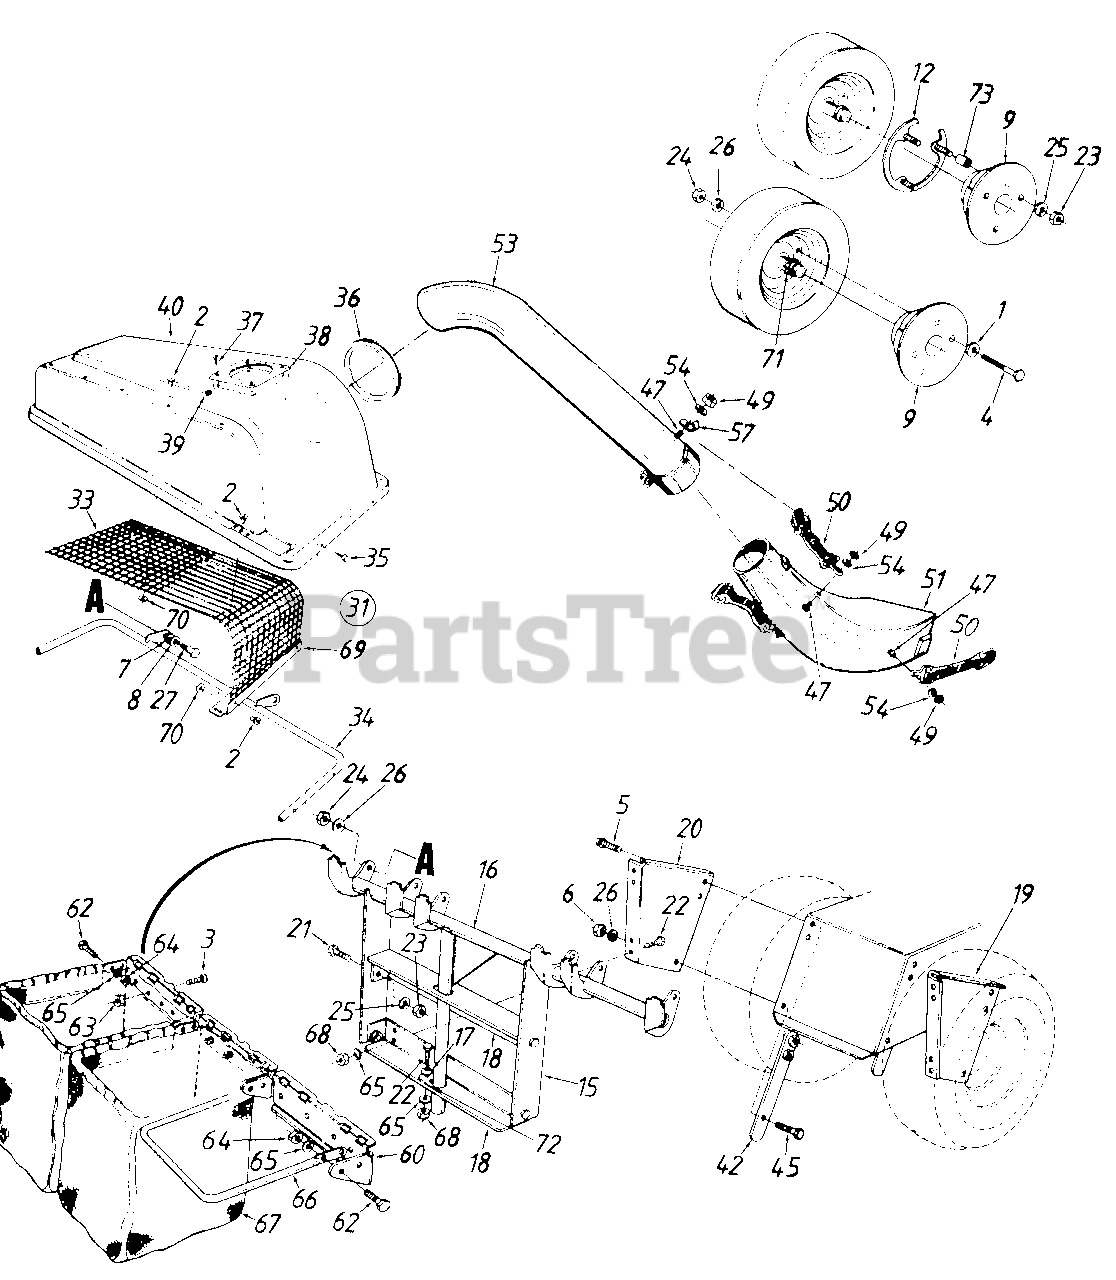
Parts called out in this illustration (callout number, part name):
1	Fl-Wash. .385" I.D.
2	Pop Rivet
3	Truss Mach. Scr. #10-24 x .38" Lg.
4	Hex Bolt 3/8-16 x 4.5" Lg.
5	Hex Wash. Hd. Tap Scr. 5/16-18 x .62
6	Hex Nut 3/8-24 Thd.
7	Bell-Wash. .515" l.D.
8	Fl-Wash. .510" l.D.
9	Wheel Weight
12	Wheel Weight Snap Ring
15	Catcher Support Tube Mtg. Brkt.
18	Catcher Latch and Support Brkt.
22	Hex Bolt 1/4-20 x .62" Lg.- 0 Grade 5
23	Hex Nut 5/16-18 Thd.
24	Hex Nut 3/8-16 Thd.
25	L-Wash. 5/16" I.D.
26	L-Wash. 3/8" l.D.
27	Shld. Bolt 3/8-16 x .500" Dia.
31	Grass Catcher Cover Ass'y. Comp.
37	Truss Mach. B-Tap Scr. #10 x .5" Lg
38	Plastic Plate
39	Speed Nut
40	Grass Catcher Cover
47	Hex Bolt 1/4-20 x .50" Lg.
49	Hex Ins. L-Nut 1/4-20 Thd.
50	Retainer Strap Ass'y.
51	Discharge Chute
53	Catcher Elbow Tube
54	L-Wash. .270n l.D. x .57" O.D.
57	Retainer Hook Brkt.
62	Hex Bolt 1/4-28 x .75n Lg.
63	Hex Sems Nut #10-24 Thd.
64	Hex Nut 1/4-28 Thd.
65	L-Wash. 1/4" l.D.
66	Catcher Bag Frame
67	Grass Catcher Bag
68	Hex Nut 1/4-20 Thd.
71	Foam Strip 1-1/8" x 1-1/2" x 3/8
